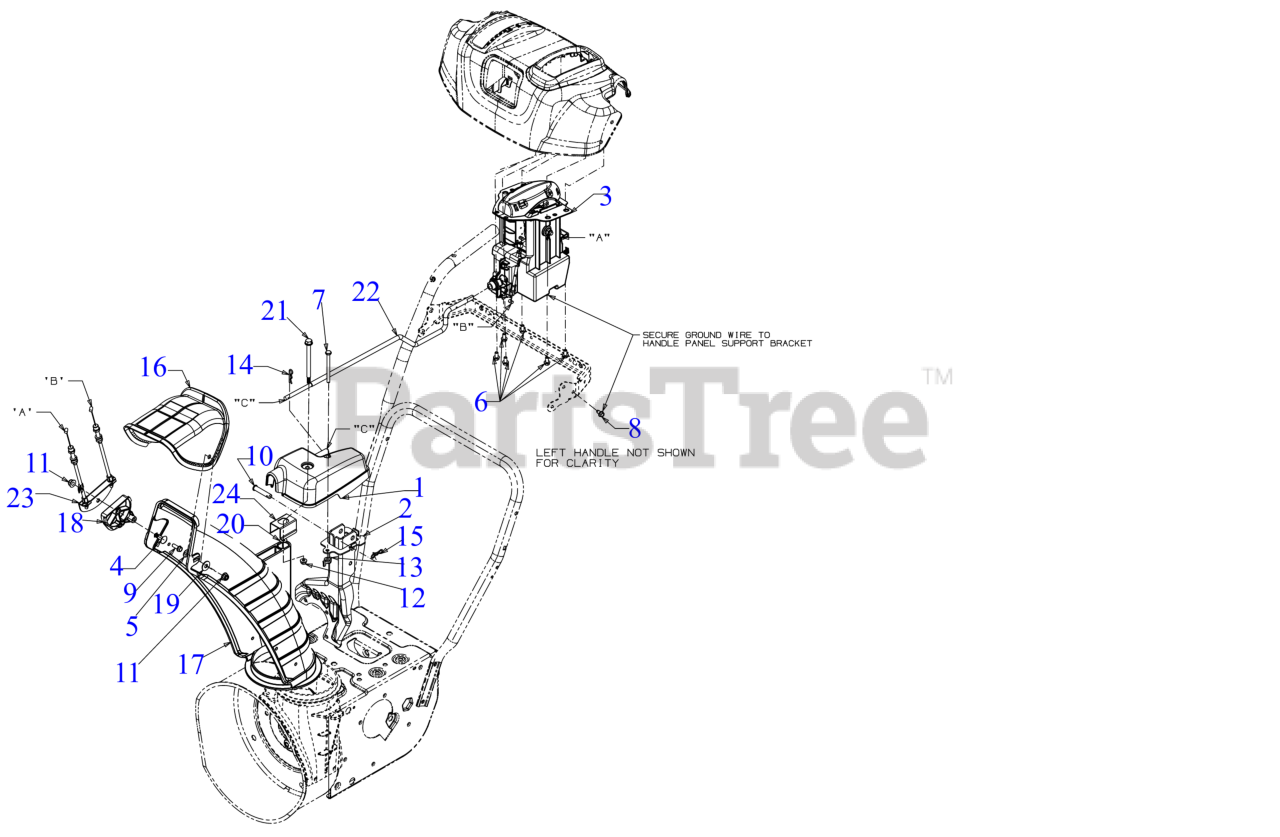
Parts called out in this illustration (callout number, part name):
1	WORM GEARBOX ASSEMBLY
3	CHUTE CONTROL ASSEMBLY-4-WAY ELECTRIC
4	CARRIAGE BOLT 5/16-18 x 1.50
5	CARRIAGE BOLT 5/16-18 x 1
6	HEX SCREW 1/4-15 x .50
7	SCREW 1/4-20 x 3.0 GR5
8	SCREW 1/4-20 X.500
9	SCREW 1/4-15 x .750
10	CLEVIS PIN 3/8 x 1.87
11	FLANGE LOCK NUT 5/16-18
12	FLANGE LOCK NUT
13	WING NUT 1/4-20
14	INTERNAL COTTER PIN-1/2 DIA
15	BOW TIE COTTER PIN 1/4-5/16
16	UPPER CHUTE
17	LOWER CHUTE 5"
18	CABLE CHUTE GUIDE
19	FLAT WASHER
20	FLAT WASHER
21	SHOULDER SCREW
22	ELECTRIC CHUTE CRANK ROD
23	CABLE BRACKET
24	CHUTE BRACKET
